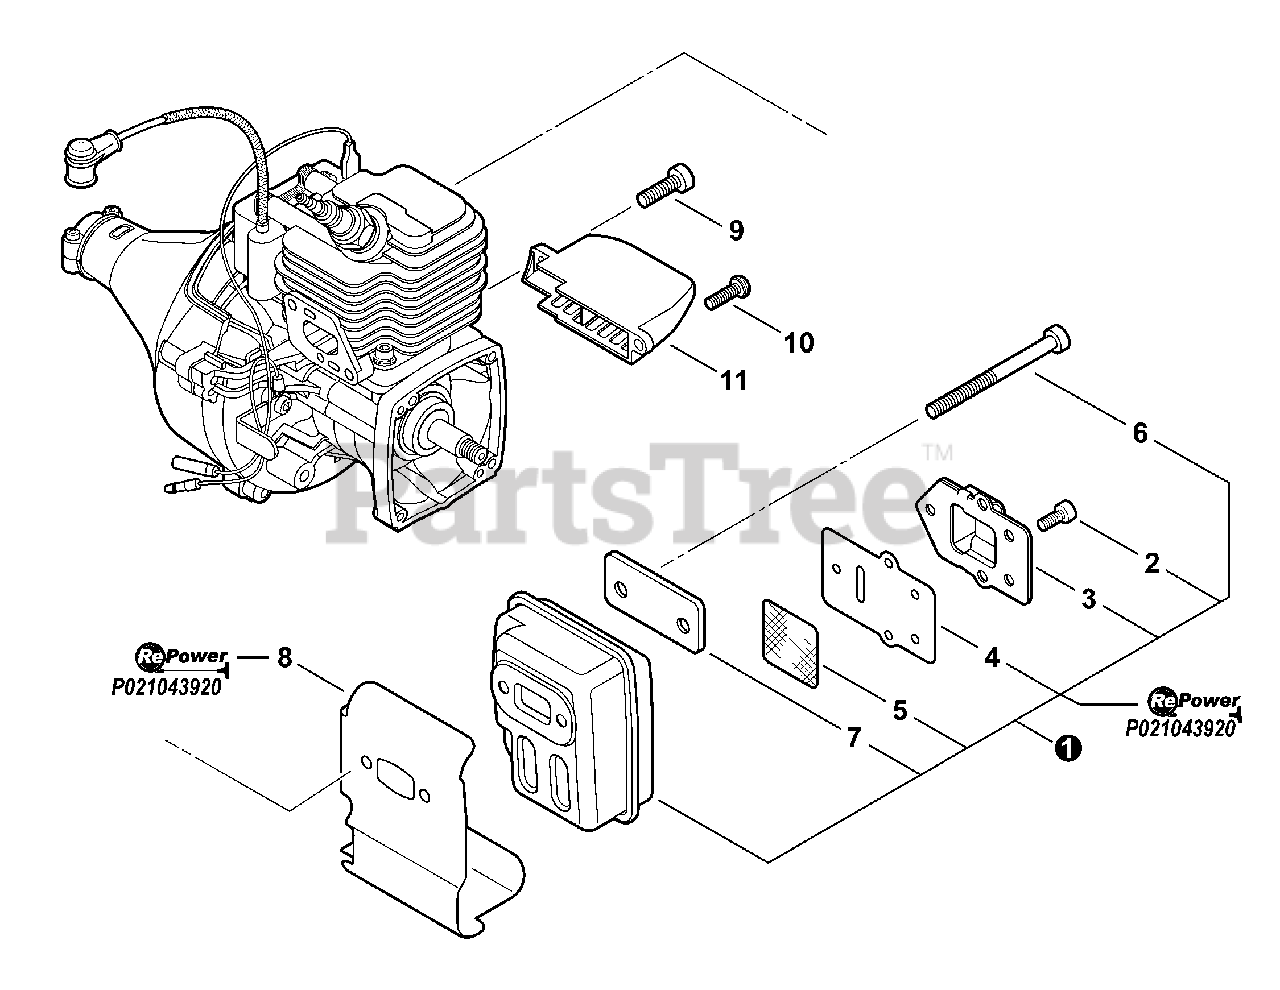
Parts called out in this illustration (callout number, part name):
1	MUFFLER ASY
2	SCREW - 4×8 -- TORX
3	GUIDE, EXHAUST
4	GASKET, EXHAUST
5	SCREEN, SPARK ARRESTER
6	SCREW - 5×55
8	SHIELD, EXHAUST
9	SCREW - 5×16 -- TORX
10	SCREW - 5×16 -- TAPPING
11	DUCT, AIR
